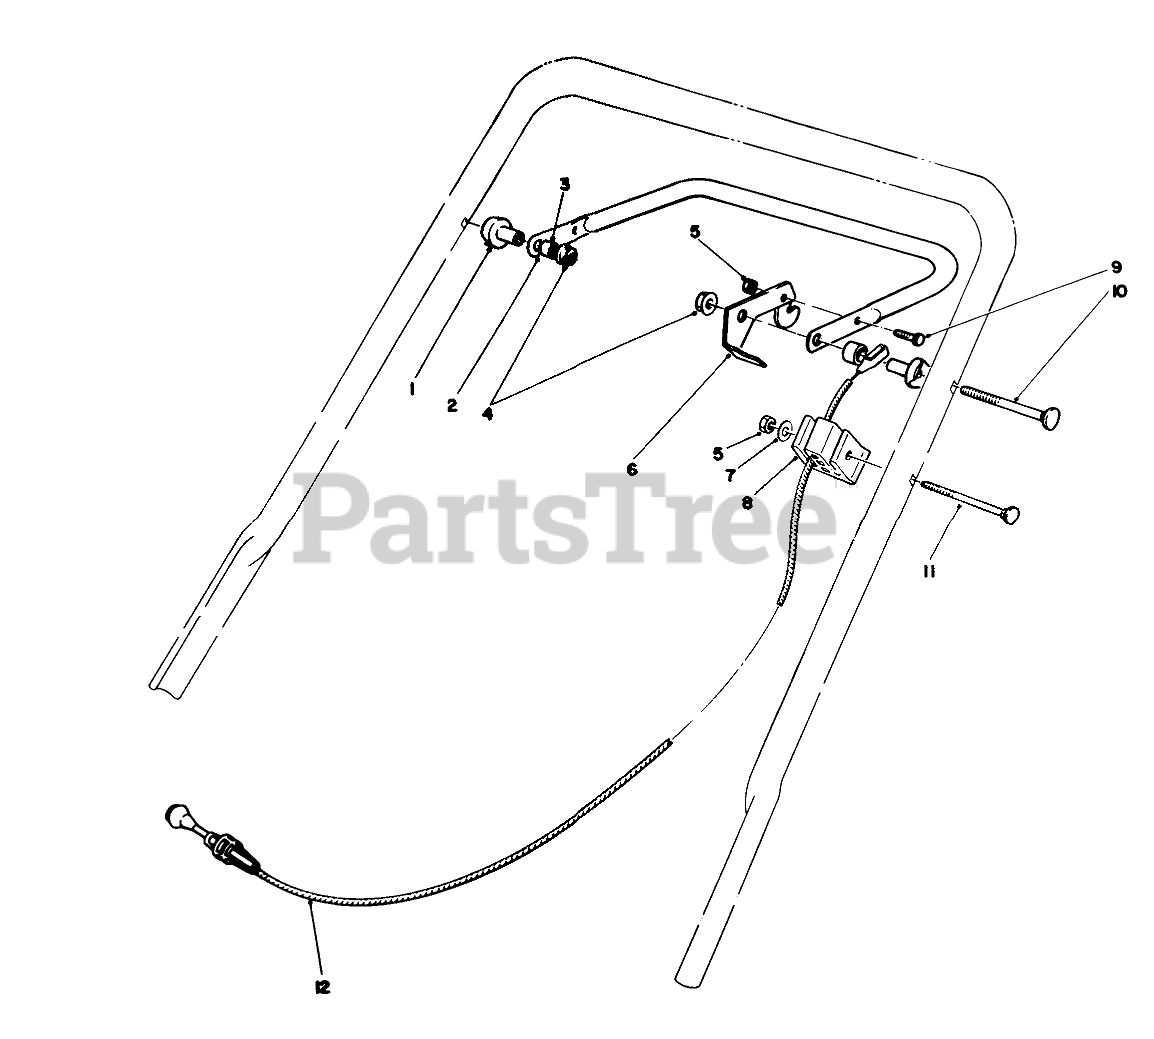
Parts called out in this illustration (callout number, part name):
1	SPACER-SUPPORT
2	Bar-Control
3	SPACER-NYLON
4	NUT-LOCK, NI
5	NUT-LOCK, NI
6	LEVER-CONTROL
7	WASHER-FLAT
8	SUPPORT-CABLE
9	SCREW-HH
10	5/16-18 X 2 HNDLE SCREW
11	HANDLE SCREW
12	BRAKE CABLE
